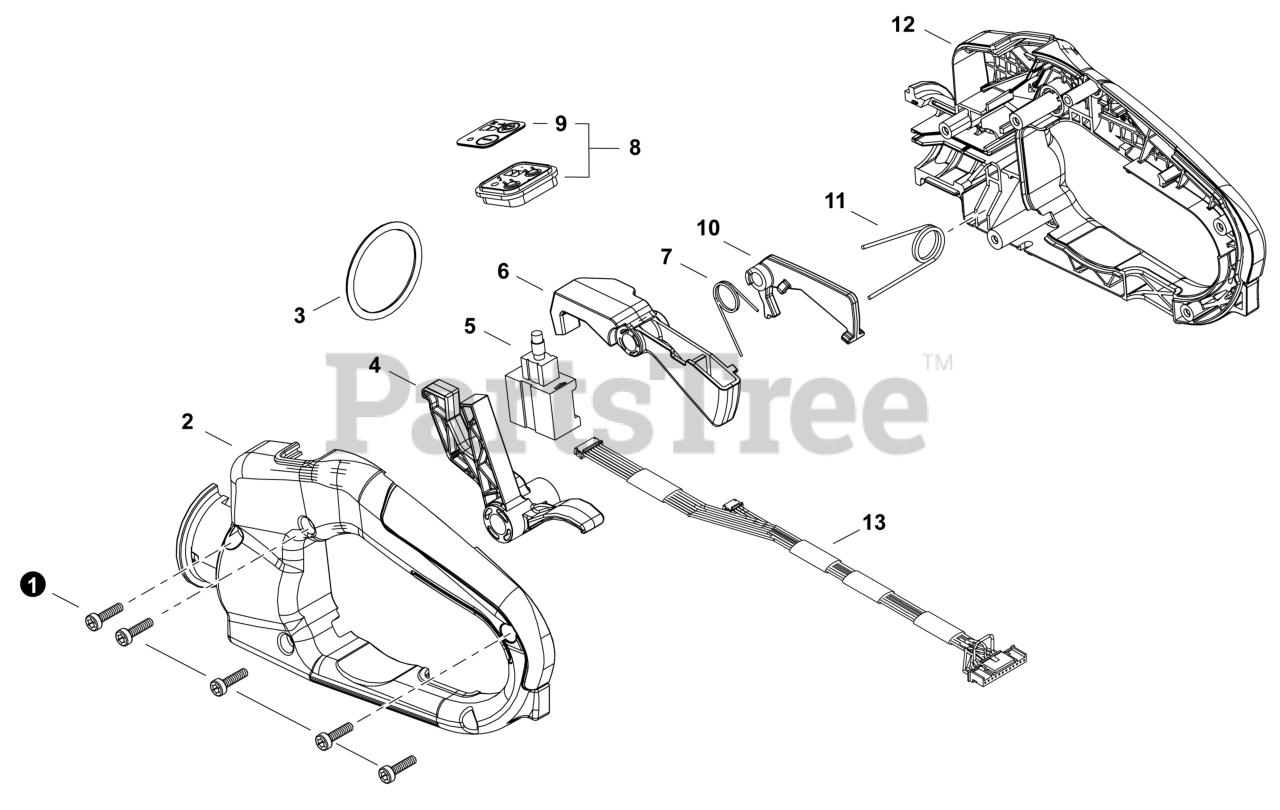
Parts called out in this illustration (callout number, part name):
1	BOLT, TORX 4x16
2	HANDLE, CONTROL - LEFT
4	TRIGGER, THROTTLE
5	SWITCH, SPEED CONTROL
7	SPRING, TORSION
8	SWITCH ASSY, ON-OFF
9	LABEL - SWITCH
10	LOCKOUT, THROTTLE
11	SPRING, TORSION
12	HANDLE, CONTROL - RIGHT
13	HARNESS, WIRE - SWITCH
